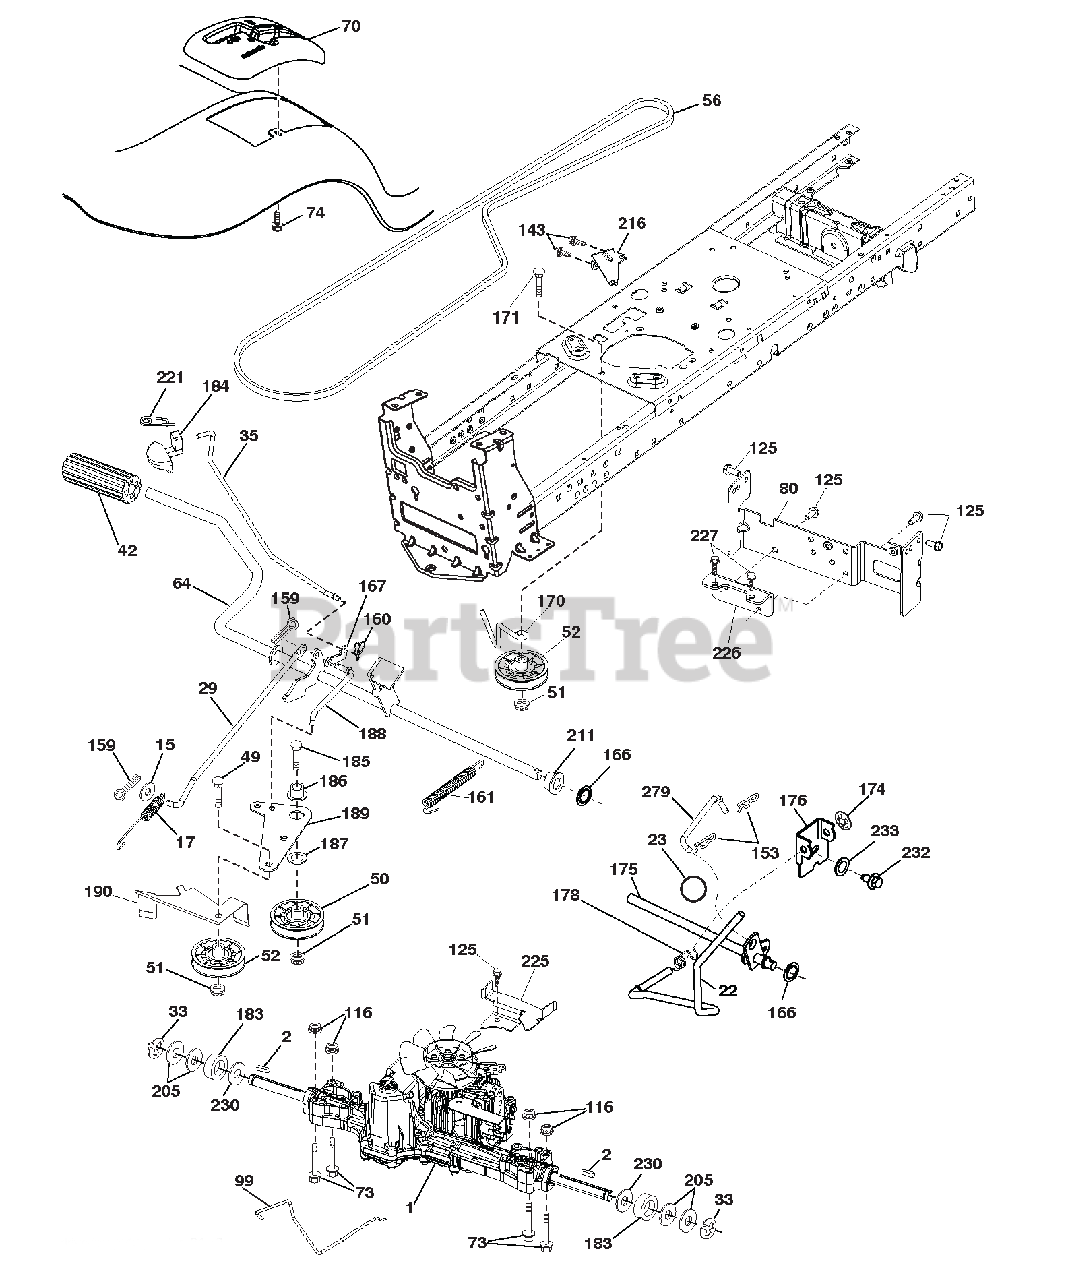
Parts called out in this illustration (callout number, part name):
1	TRANSAXLE, TUFFTORQ K46 BA
2	KEY.SQUARE.2.0 X .1845/.1865
15	WASHER.13/32 X 13/16 X 16 GA.
17	SPRING.BRAKE.K46.GREEN
22	ROD.SHIFT.FENDER.TLT.2006
23	KNOB DELUXE
29	ROD.BRAKE.K46
33	E-RING.#5133-75
35	ROD, BRAKE, PARK
42	COVER PEDAL BLK ROUND
49	BOLT.RDHD.3/8-16UNCX1-3/4.GR5
50	IDLER.FLAT.910"OFFSET
51	Nut, Hex, Flangelock 3/8-16
52	IDLER.V-GROOVE.910"OFFSET
56	V-BELT.MOWER.92.40.42/K46
64	SHAFT ASM.PEDAL.BRAKE CONTROL
70	CONSOLE SHIFT STL HYD BLACK TX
73	BOLT 5/16-18 X 2 1/2 G.5
74	SCREW.HEX.WSH.HI-LO.1/4X1/2UNC
80	STRAP.TORQUE.K46/18"TEX
99	ROD.SPRING.BYPASS.K46.LT.Z
116	Nut, Lock Hex Flange 5/16-18 u
125	SCREW.5/16-18X3/4.SMGML.TAP/BL
143	SCREW.THDROL.5/16-18 X 1/2TYTT
153	RETAINER SPRING
159	PIN.COTTER.1/8 X 3/4.CAD.
160	RETAINER.CLIP(M).DIA.290
161	SPRING.RETURN.CLUTCH.6.75
166	NUT PUSH .625
167	LATCH.BRAKE.PARKING
170	KEEPER BELT CENTERSPAN
171	BOLT.RD.HD.SQ.NK.3/8-16UNC X 2
174	NUT.PUSH..500
175	SHAFT ARM SHIFT
176	ARM.CLEVIS.ROD.SHIFT
178	SPRING.SHIFT.GT.2006
183	SPACER.AXLE.HYDRO/PEERLES
184	HANDLE PARKING BRAKE
185	BOLT.RDHD.3/8-16UNC X2-3/4 GR5
186	SPACER.RETAINER
187	WASHER.13/32 X 2 X 10 GA.
188	LINK.CLUTCH.GROUND DRIVE
189	BELLCRANK.GROUNDRIVE.NSTG/NSTL
190	KEEPER.BELLCRANK.DRIVE.GROUND
205	WASHER.25/32 X 1-5/8 X 16GA.
211	BUSHING.SHAFT.BRAKE.HAND CONTR
216	BRACKET.PULLEY.IDLER.WTEX
221	RETAINER.SPRING.CLIP.HANDLE
225	KEEPER.BELT.TRANSAXLE.K46
226	BRACKET.MOUNT.TORQUE.K46.TLT
227	SCREW 5/16-18 X 3/4
230	WASHER.HARDEN..793 X 1.637X060
232	BOLT.FIN HEX.7/16-14X1 GR5
233	WASHER.SERRATED
279	LINK SHIFT T/A
